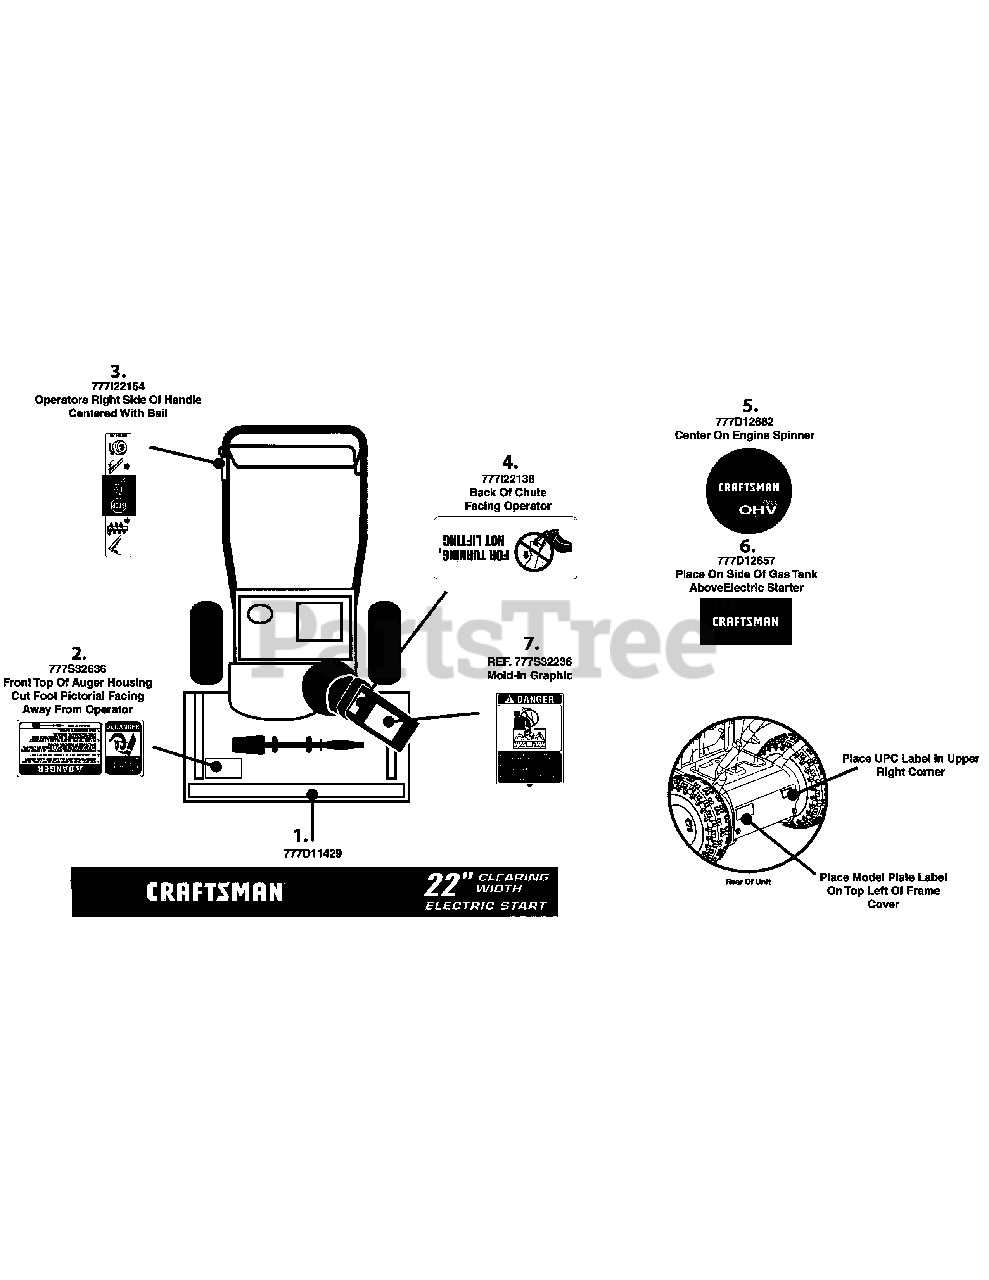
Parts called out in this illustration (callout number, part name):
1	LABEL-SNOW HSG CRAFTSMAN
2	LABEL-SNOW HOUSING
3	LABEL-HANDLE
4	LABEL-CHUTE
5	LABEL-SNOW MTD ENGINE CRAFTSMAN
6	LABEL-ENGINE GAS TANK CRAFTSMAN
7	LABEL:SNOW CHUTE
